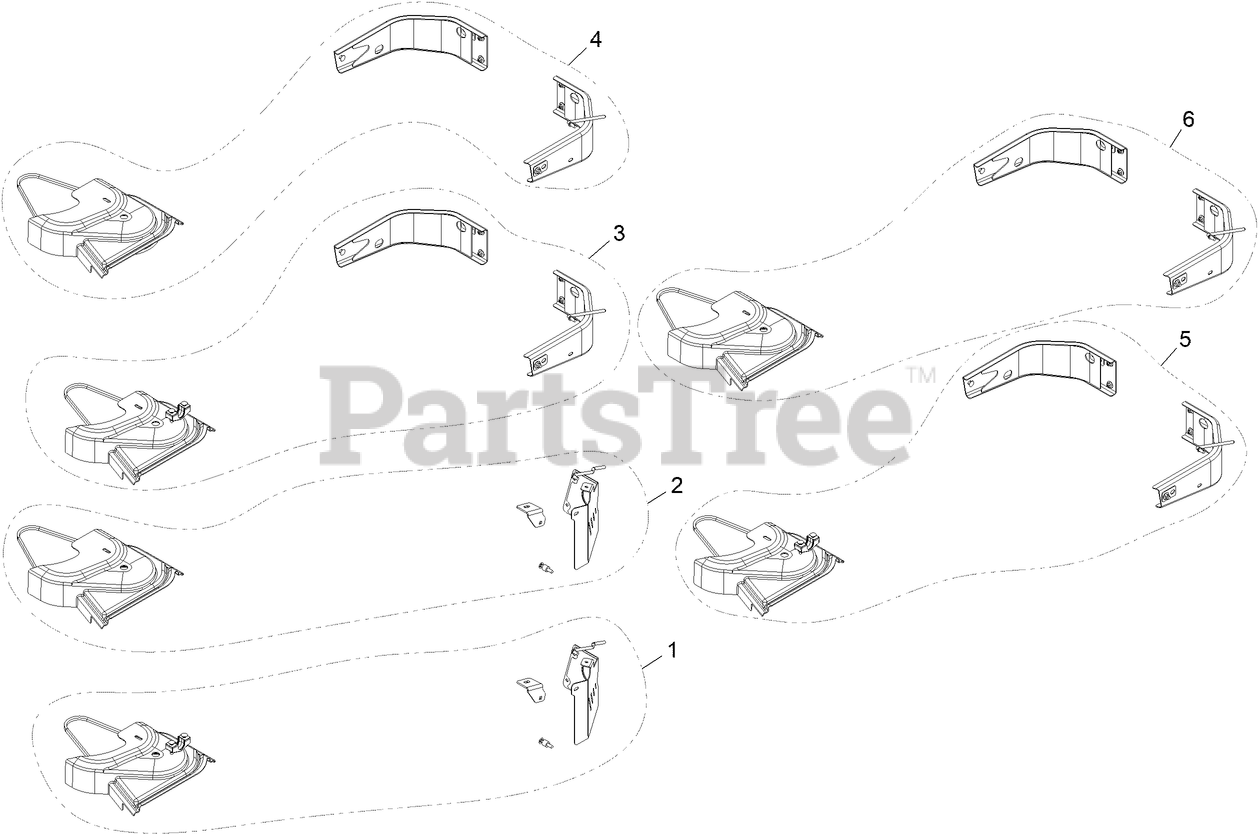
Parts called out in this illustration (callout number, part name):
1	Kit,Uv Drive 606
2	Kit,Uv Drive 726
3	Kit,Uv Drive 604 Splined
4	Kit,Uv Drive 724 Splined
5	Kit,Uv Drive 606
6	Kit,Uv Drive 726
